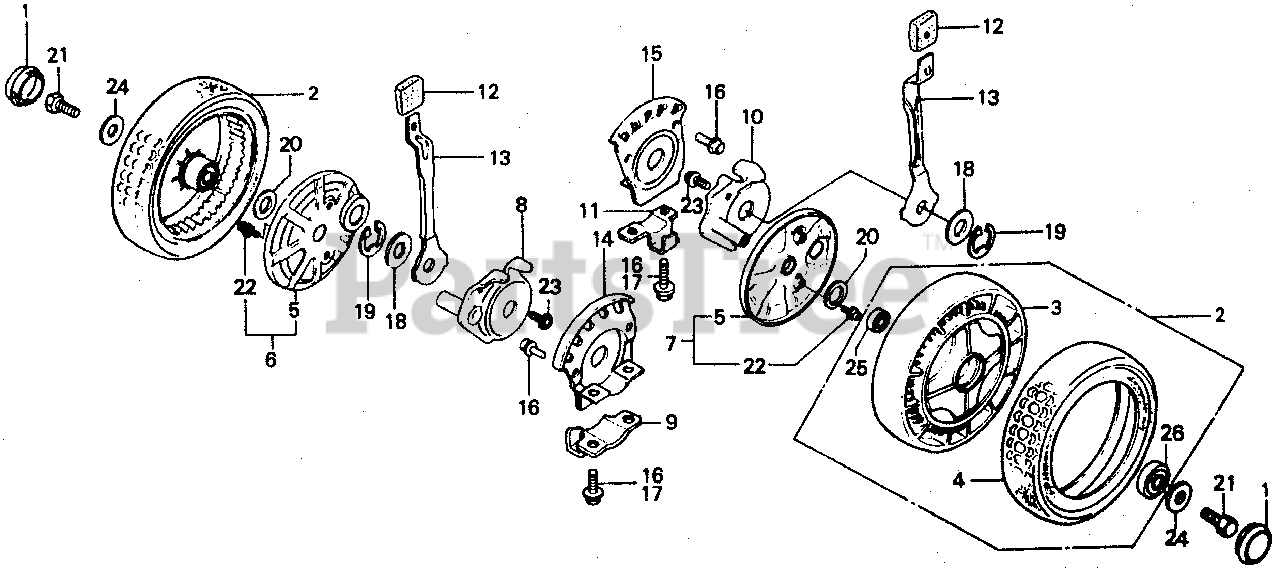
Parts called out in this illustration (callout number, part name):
1	CAP, WHEEL
2	WHEEL ASSY., RR. *NH31* (MCKINLEY WHITE) (NOT AVAILABLE)
3	HUB, RR. WHEEL *NH31* (MCKINLEY WHITE)
4	TIRE, RR. (8INCH)
5	COVER, WHEEL (NOT AVAILABLE)
6	COVER, R. WHEEL
7	COVER, L. WHEEL
8	ARM, R. RR. ADJUSTING
9	HOLDER, R. ADJUSTING ARM (NOT AVAILABLE)
10	ARM, L. RR. ADJUSTING
11	HOLDER, L. ADJUSTING ARM
12	GRIP, ADJUSTER
13	PLATE, RR. ADJUSTING (NOT AVAILABLE)
14	PANEL, R. RR. ADJUSTING
15	PANEL, L. RR. ADJUSTING
16	BOLT, FLANGE (6X12) (CT200)
17	BOLT, FLANGE (6X20) (CT200)
18	WASHER, PLAIN (22MM)
19	E-RING (19MM)
20	WASHER, THRUST (15MM)
21	BOLT, HEX. (8X12)
22	SCREW-WASHER (4X8)
23	SCREW-WASHER (4X14)
24	WASHER, PLAIN (8MM)
25	BEARING, RADIAL BALL (6002UU)
26	BEARING, RADIAL BALL (6202UU)
